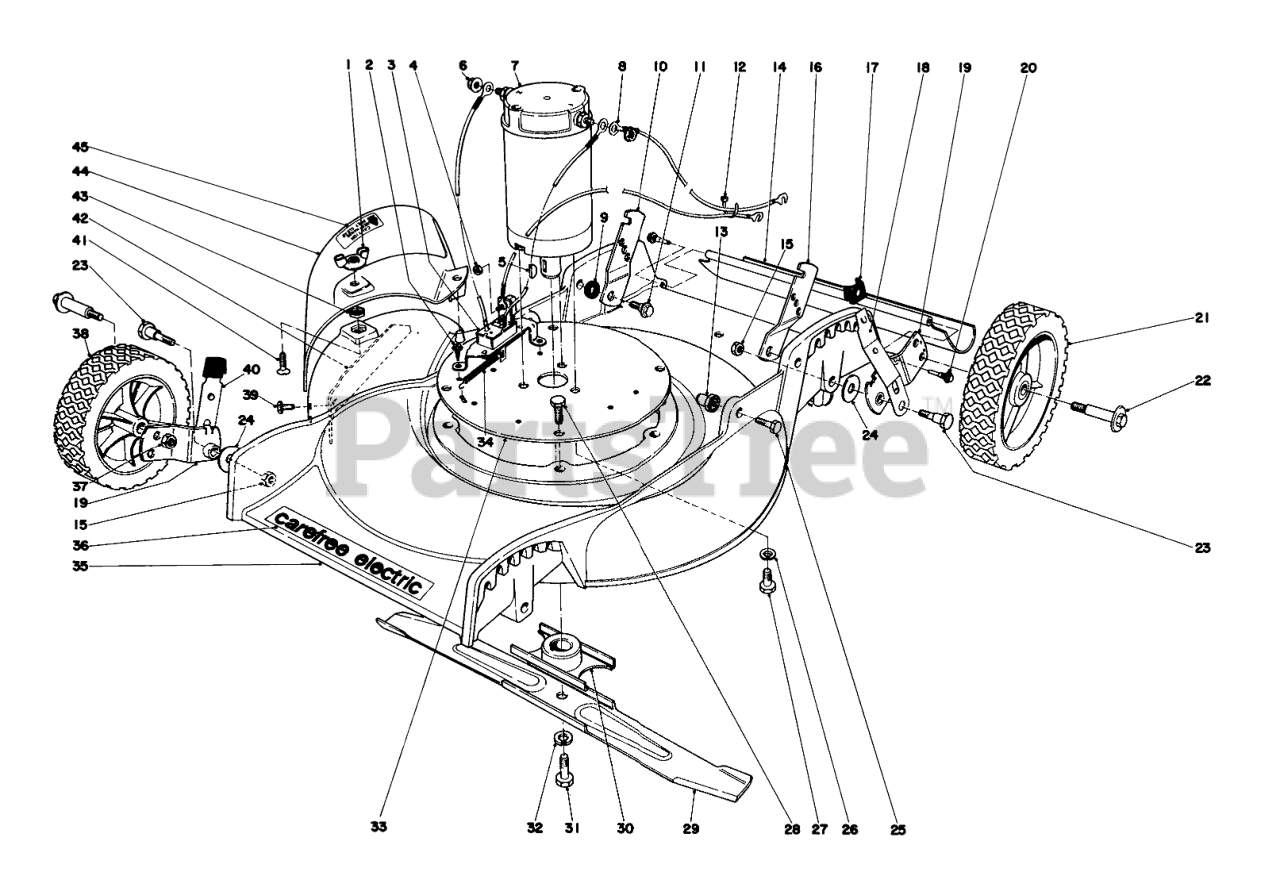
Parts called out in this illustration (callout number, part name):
1	NUT-WING SPECL
2	SCREW-HWHTF
3	Switch
4	NUT-HEX
5	KEY-WOODRUFF
6	Nut Belleville
7	Motor
8	Lead-Ground (Black)
9	SPACER
10	Latch Handle R.H.
11	SCREW-SHOULDER
12	TIE-CABLE
13	HANDLE PIVOT NUT
14	Rear Safety Shield
15	Nut
16	Latch Handle L.H.
17	KNOB-ARM
18	Spring Arm Assy. Rear
19	Pivot Arm Assy. "A"
20	SAFTEY SHIELD SCREW
21	WHEEL ASM 7
23	Pivot Bolt
24	WASHER-PIVOT
25	SCREW-HH
26	WASHER-LOCK
27	SCREW-HH
28	SCREW-HWHTF
29	Blade
30	Blade Retainer
31	Capscrew
32	WASHER-LOCK
33	Plate Motor Mount
34	Spring Extension-Return
35	Housing
36	Decal-Deck
37	Nut
38	Wheel & Tire Assembly, Front
39	SCREW-HWH
40	Spring Arm Assy. Front
41	Flat Head Screw
42	Deflector Bar
44	Deflector Assy. (Incl. Ref. #45)
45	Decal
